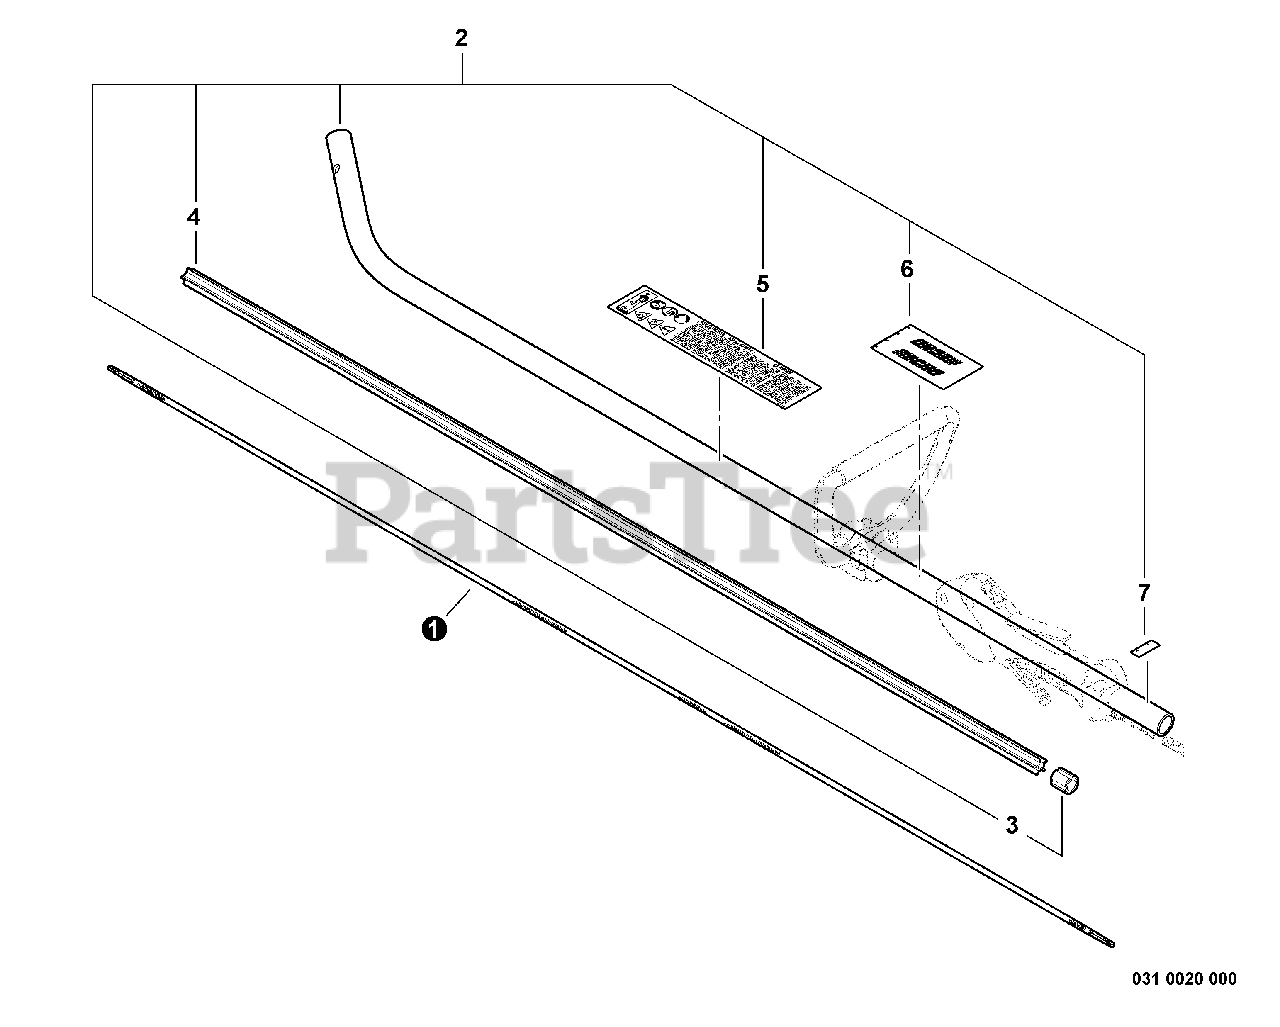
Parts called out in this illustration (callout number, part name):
1	DRIVESHAFT - FLEXIBLE
2	MAIN PIPE ASSY
4	LINER, FLEXIBLE 21.6×1420
5	LABEL, CAUTION
6	LABEL, HANDLE LOCATION
7	LABEL - ALIGNMENT
